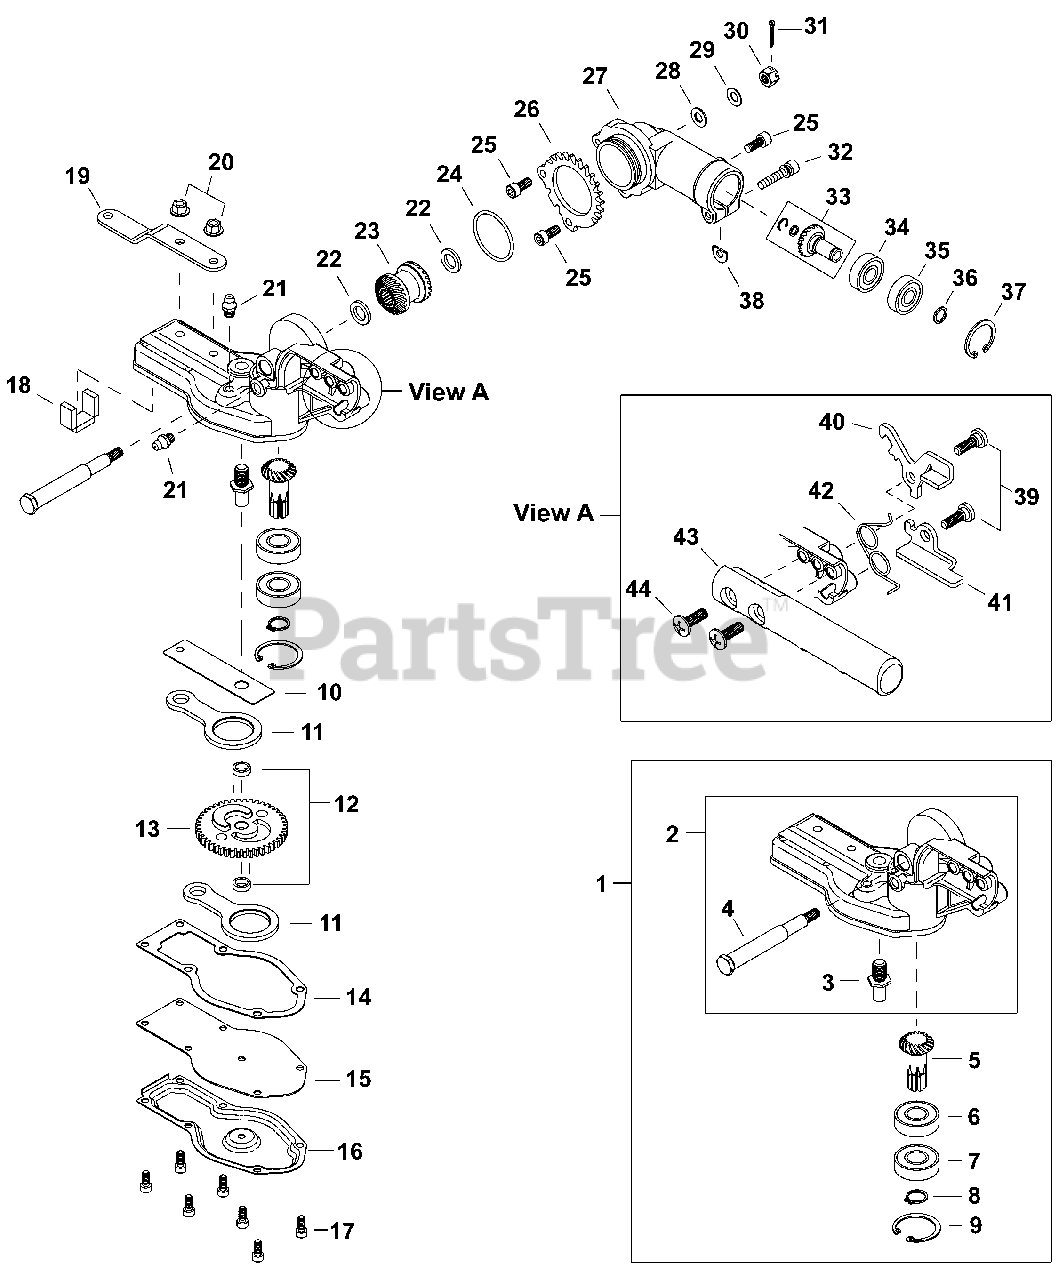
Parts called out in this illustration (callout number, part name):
1	GEAR CASE HOUSING KIT
2	GEAR CASE HOUSING ASSY
3	MAINSHAFT
5	SHAFT, PINION
6	BEARING, BALL 6001
7	BEARING, BALL 6001ZZ
8	RING, SNAP Ø12
9	RING, SNAP Ø28
10	PLATE, GUIDE
12	SPACER Ø11ר8×3.4
13	GEAR, CAM
14	GASKET, GEAR CASE
16	COVER, GEAR CASE
17	BOLT 4×10
18	PACKING, FELT
19	BRACKET, CUTTER
20	NUT, FLANGE M5
21	FITTING, GREASE
22	COLLAR Ø16ר10×L= 2
23	GEAR, BEVEL
25	BOLT 5×12
26	RING, LOCKING
27	HOUSING, UPPER GEAR CASE
28	WASHER 6.5×13×1
29	WASHER, CONE M6
31	PIN, COTTER Ø1.6×15
32	BOLT M5×25
33	PINION SET, BEVEL
34	BEARING, BALL 609
35	BEARING, BALL 609ZZ
36	RING, SNAP
37	RING, SNAP Ø24
38	D-WASHER
39	BOLT M6
40	LEVER, LOCK
41	RELEASE, LOCK
42	SPRING, TORSION
43	LEVER, ADJUSTMENT
44	SCREW, TRUSS M6×20
